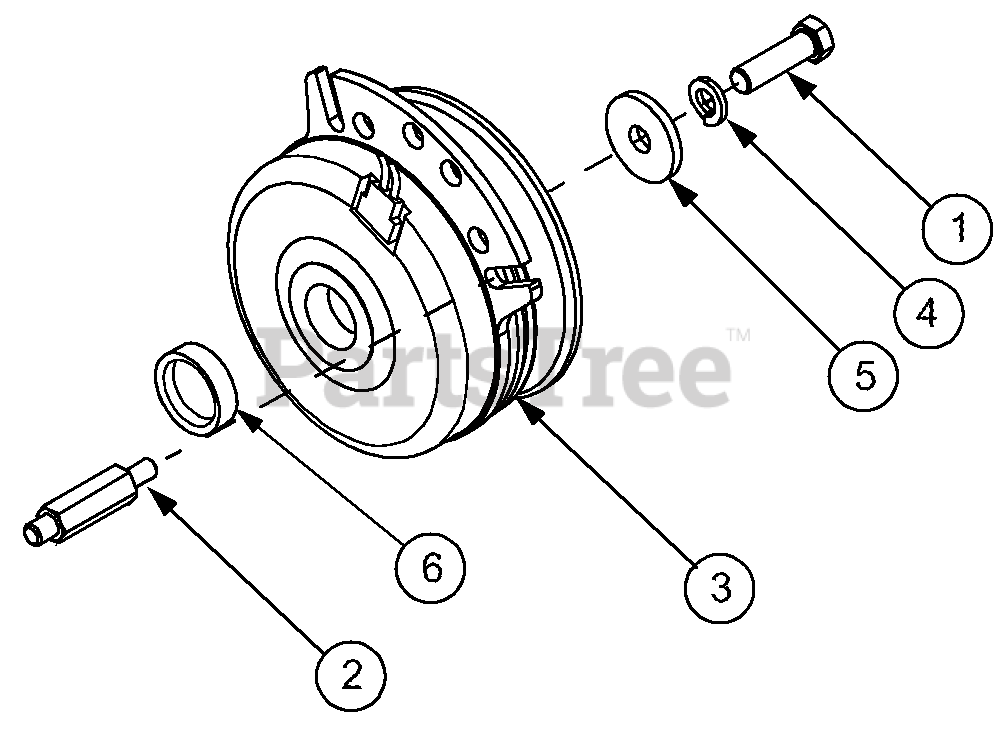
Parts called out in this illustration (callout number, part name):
1	Screw, Hex Cap, 7/16-20 x 1.5 GR5
2	Stud, Clutch Stop
3	Clutch Assy, PTO
4	Washer, Lock, 3/8
5	Washer, Flat, .445 x 1.5 x 1.72 Hdn
6	Spacer
